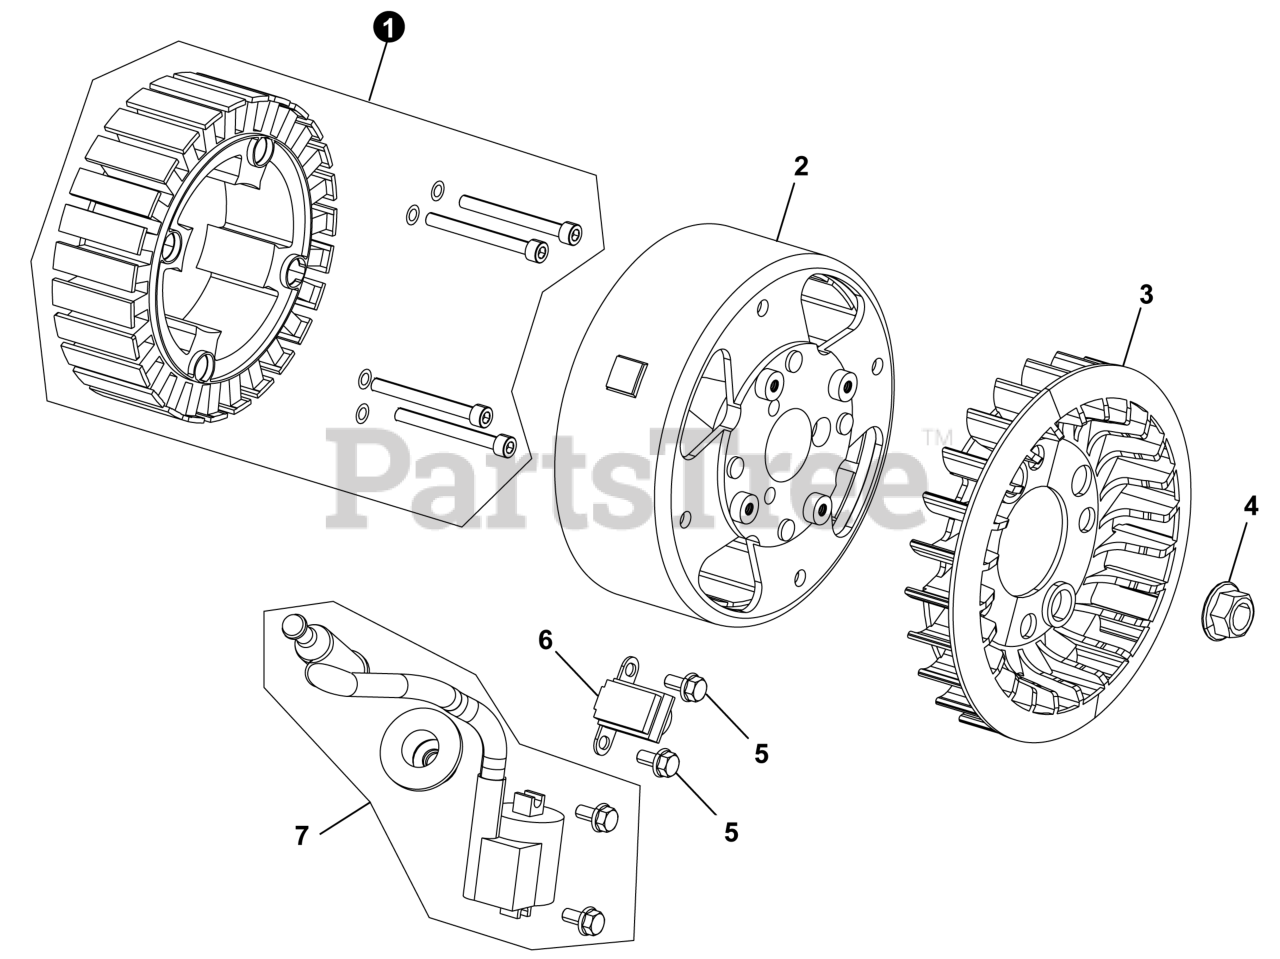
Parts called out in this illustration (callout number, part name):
2	CASE, MAGNETO ROTOR
3	IMPELLER
4	NUT, FLYWHEEL
6	TRIGGER, IGNITION
7	COIL, IGNITION
